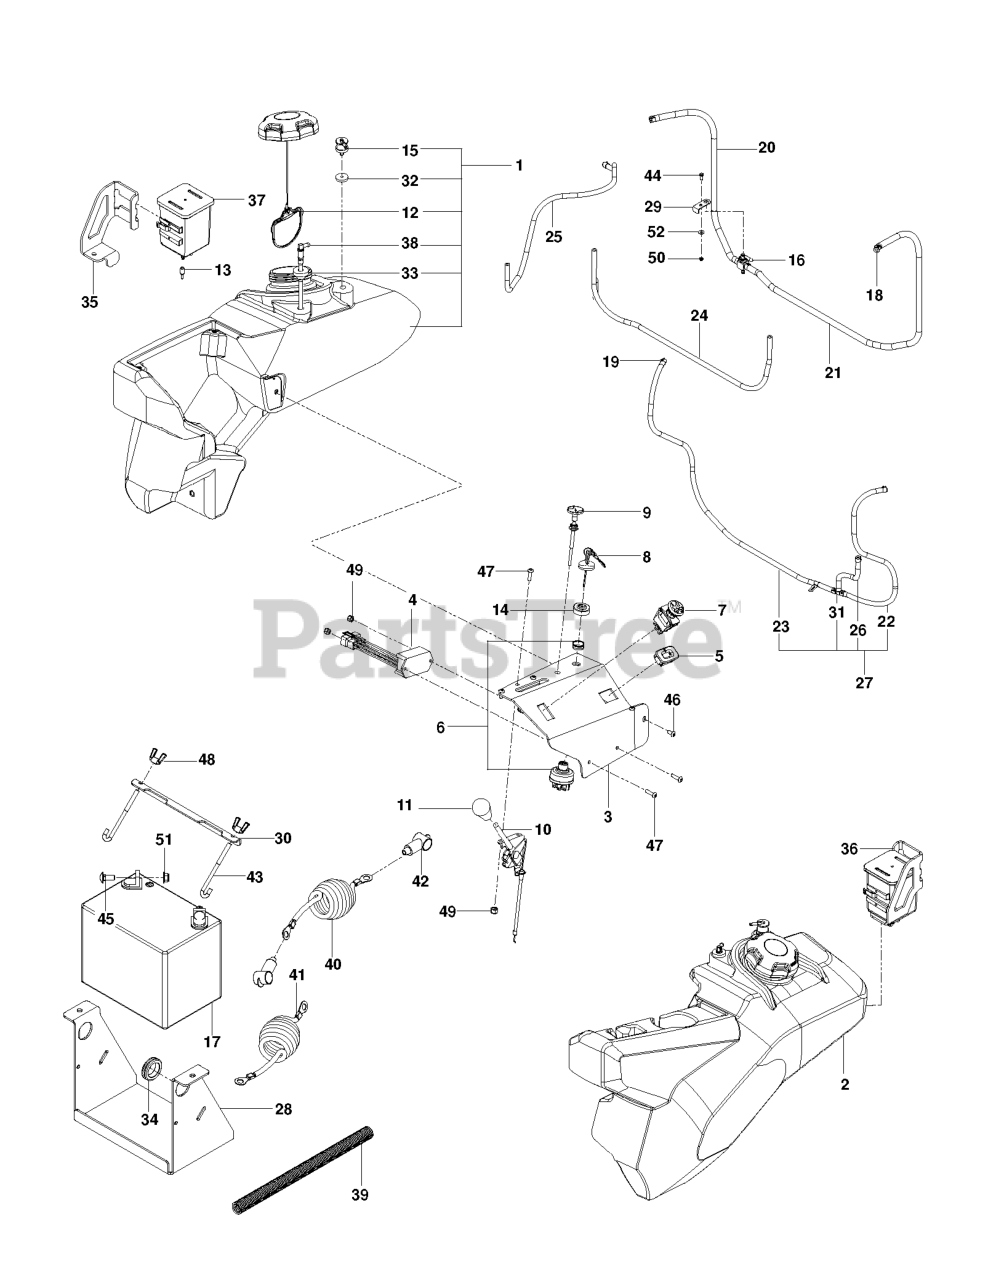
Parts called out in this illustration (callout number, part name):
1	RT FUEL TANK ASM EPA
2	LT FUEL TANK ASM EPA
3	PANEL.CONTROL.GAS.GRAY
4	TIMER, SEAT
5	RP.GUAGE.SRVCMNDR.HRMTR.
6	SWITCH, IGNITION, INDAK
7	RP SWITCH.PTO.TERMINAL.STD.RED
8	KEY, IGNITION
9	CABLE, CHOKE, 48"
10	CABLE, THROTTLE, 46"
11	KNOB - SHIFT
12	CAP, FUEL
13	CAP, VINYL
14	CAP IGNITION NUT
15	VALVE.FUEL.CHECK
16	FUEL VALVE
17	BATTERY, 12 V 330 AMP
18	CLAMP, HOSE
19	HOSE CLAMP
20	LINE, FUEL, 22"
21	LINE, FUEL, 38"
22	HOSE, 3/16" VAPOR, 21"
23	HOSE, VAPOR 3/16 X 39"
24	HOSE, VAPOR 3/16 X 30"
25	FUEL LINE 33"
26	HOSE, 3/16" VAPOR, 7-1/2"
27	ASSEMBLY, VAPOR LINE
28	BRACKET, BATTERY, BLK
29	BRACKET,FUEL VALVE, BLACK
30	BRACKET, BATTERY MOUNT
31	TEE, FUEL LINE 3/16"
32	GROMMET, CHECK VALVE
33	RUBBER GROMMET
34	RUBBER GROMMET
35	MOUNT, CANISATER, RT
36	MOUNT, CANISTER, LT
37	CANNISTER, CARBON
38	FITTING, FUEL
39	LOOM, SPLIT, CONVOLUTED
40	CABLE, POSITIVE, 55"
41	CABLE, NEG, 55"
43	HOOK, "J"
44	HCS 1/4C X 3/4 HCS
45	BOLT 5/16C X 3/4" CARRIAGE
46	SCR #10-24 X 3/8 SKT HD BLK OX
47	SCR #10-24 X .75 SKT HD BLK
48	WING NUT 1/4
49	NUT 10-24 NYLOC
50	JAM NUT 1/4C (2 2 PW01)
51	5/16-18 NYLOC FLANGE NUT
52	WASHER 1/4 FLAT
